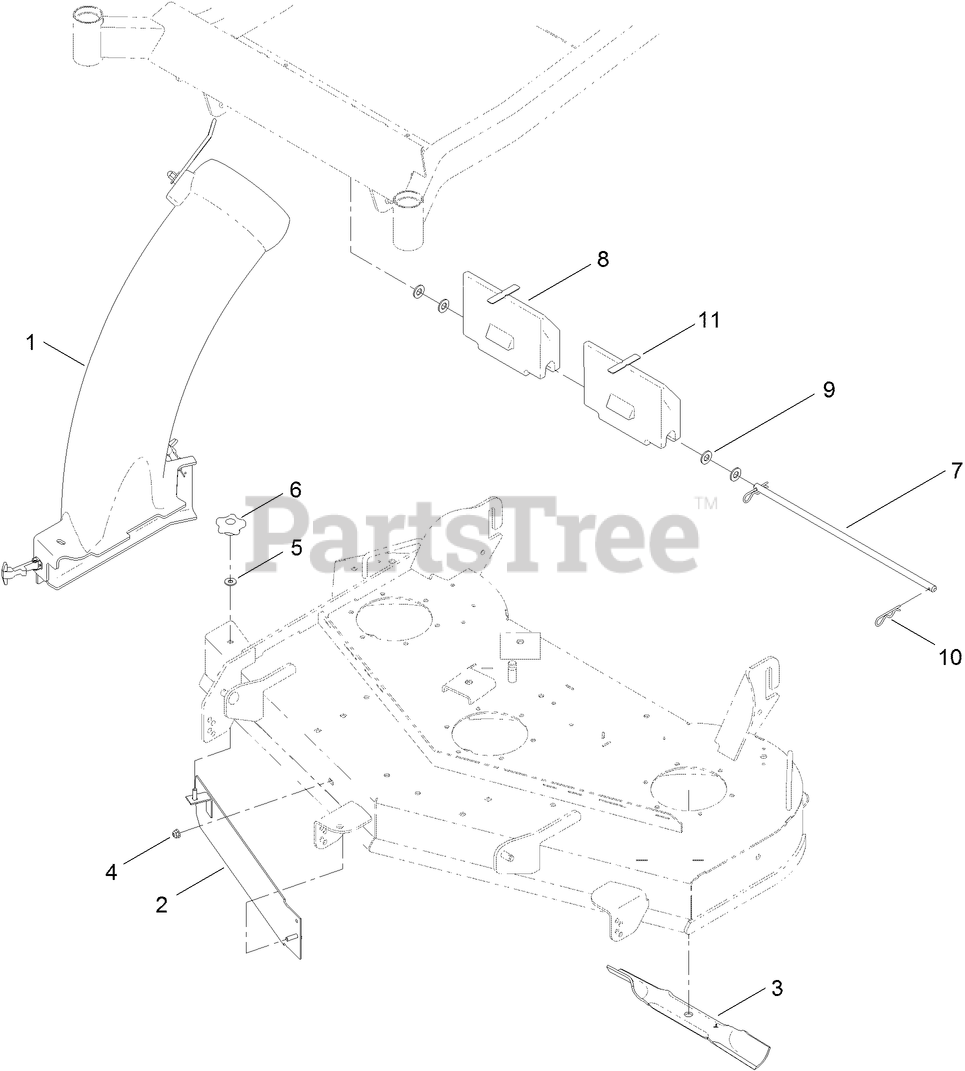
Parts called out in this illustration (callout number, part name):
1	CHUTE ASM
3	BLADE-HI LIFT, 16.50 IN
4	NUT-HF, NI
5	WASHER-FLAT
7	ROD-DECK, PIVOT
8	WEIGHT-BAGGER
9	WASHER-FLAT
10	PIN-HAIR
11	BUMPER-PAD
